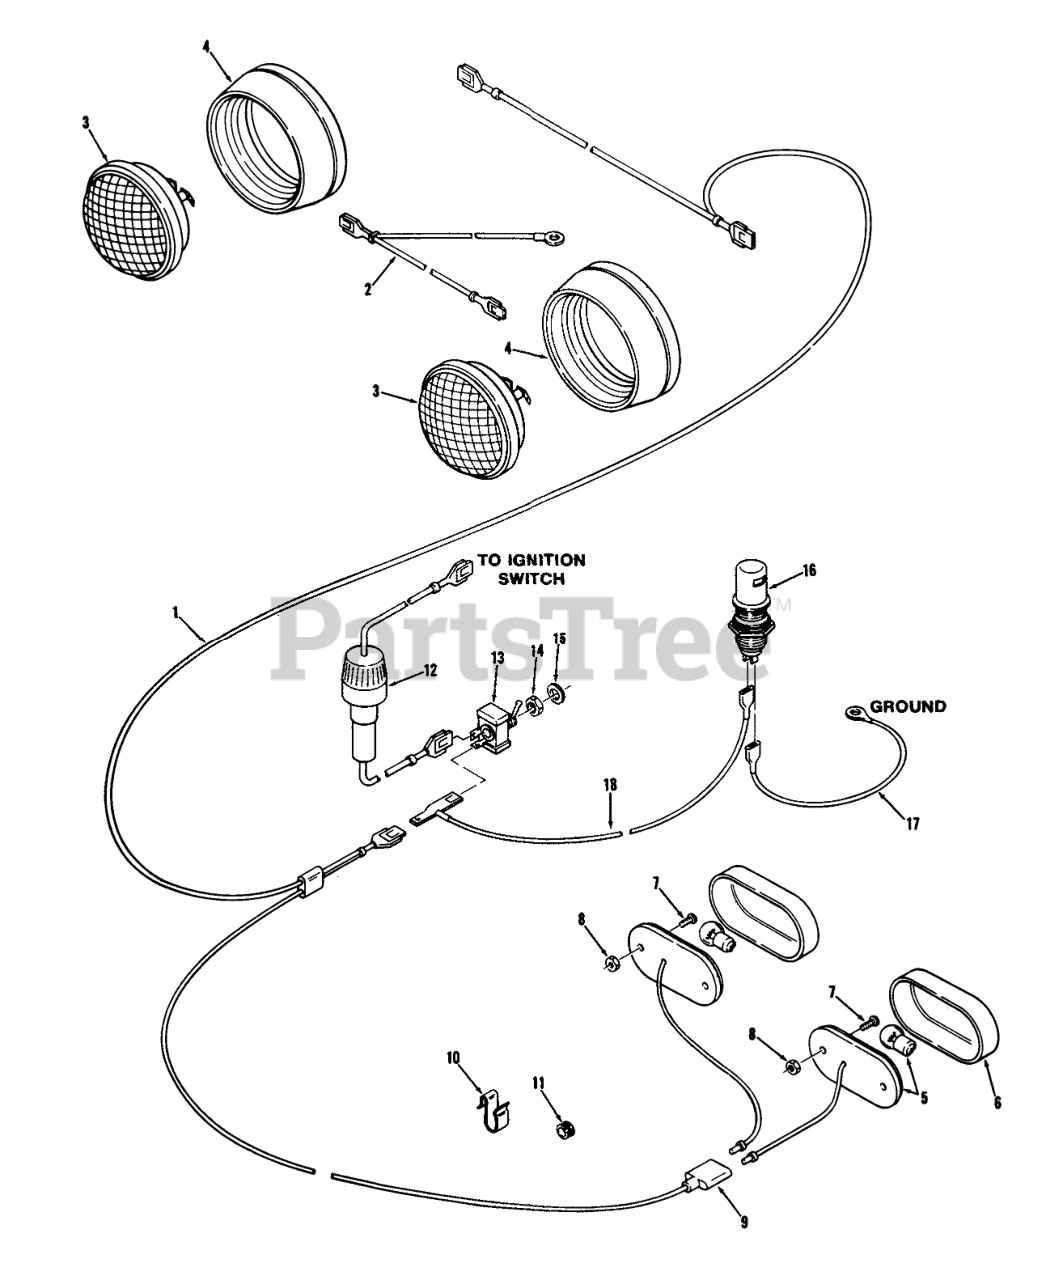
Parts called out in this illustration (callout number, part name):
1	Control Clip
2	Wire Assy
3	HEADLAMP
4	Grommet
5	BASE-TAIL LIGHT
6	Lens-Taillight
7	Screw
8	HEX NUT 10-32 E.S.
9	CONNECTOR 3 WIRE
10	SPEED CLIP
11	Grommet
12	ASSY FUSED CONNECTOR
13	SWITCH-LIGHTS
14	Nut, Knurled
15	NUT-HEX
16	LAMP-DASH
17	SY WIRE HR METER G
18	Wire Assy
